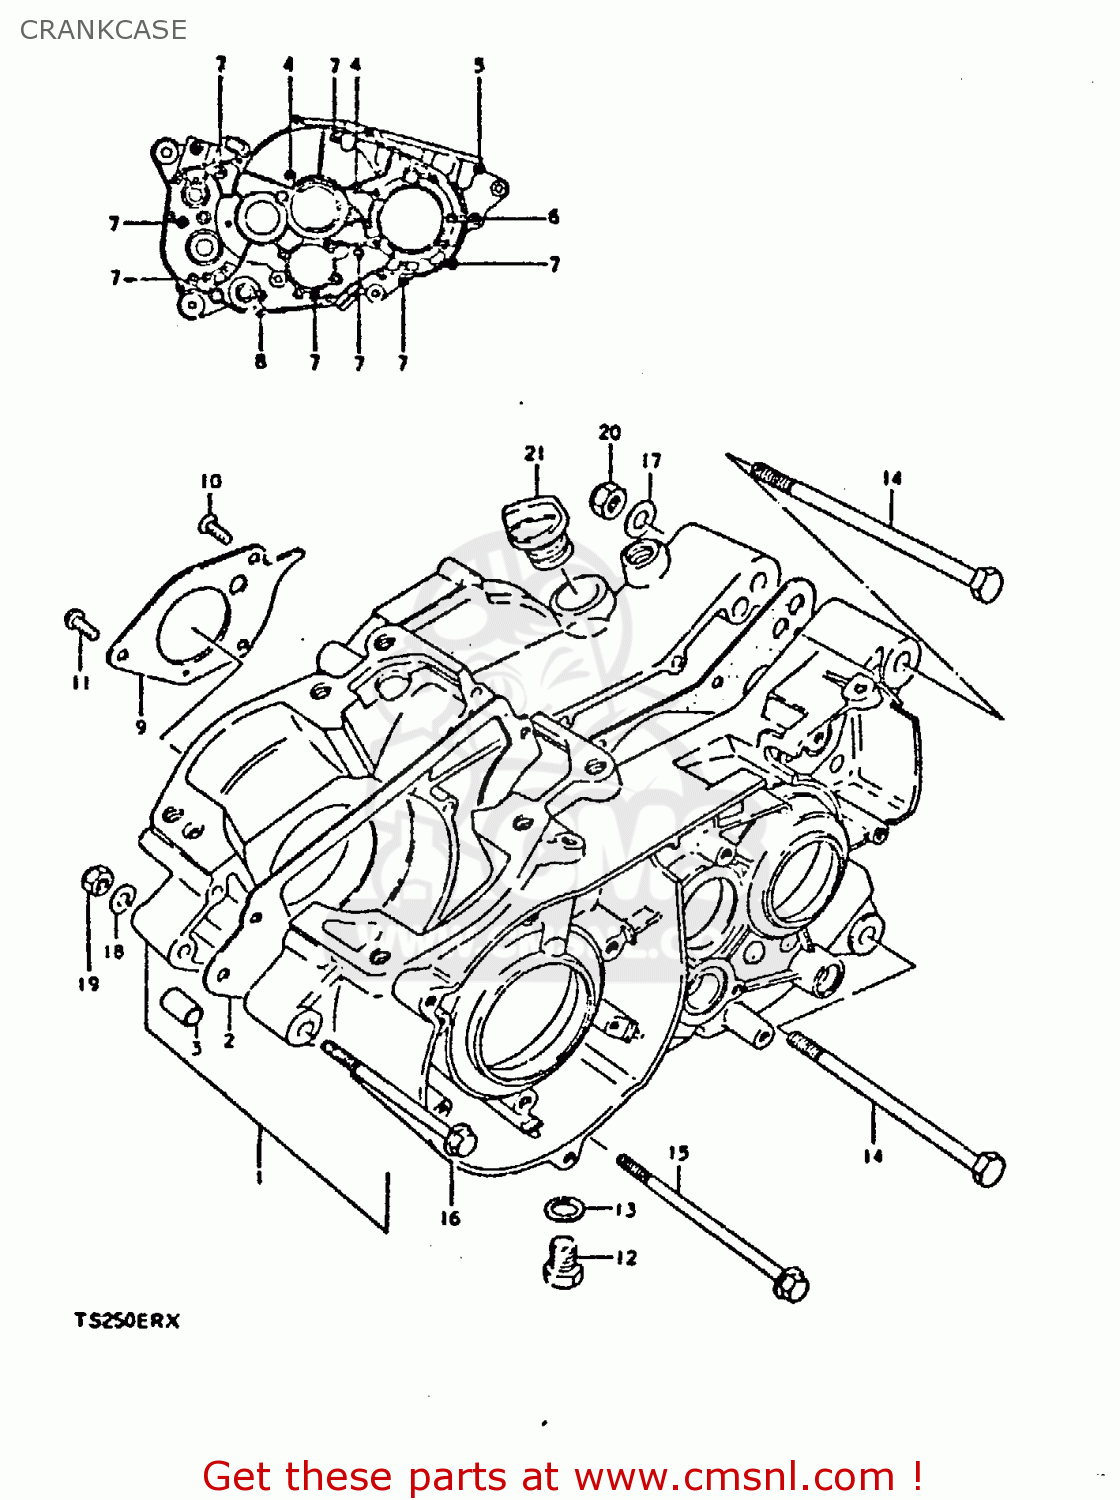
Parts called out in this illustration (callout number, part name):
1	CRANKCASE SET
2	GASKET,CRANKCASE (MCA)
3	PIN
4	SCREW
5	SCREW 6X65
6	SCREW
7	SCREW (6X45)
8	SCREW (6X35)
9	PLATE,OIL RESERVOIR
10	SCREW
11	SCREW
12	PLUG
13	GASKET(14X19.2X2) (NAS)
14	BOLT
15	BOLT
16	BOLT
17	WASHER
18	WASHER
19	NUT
20	NUT
21	PLUG
